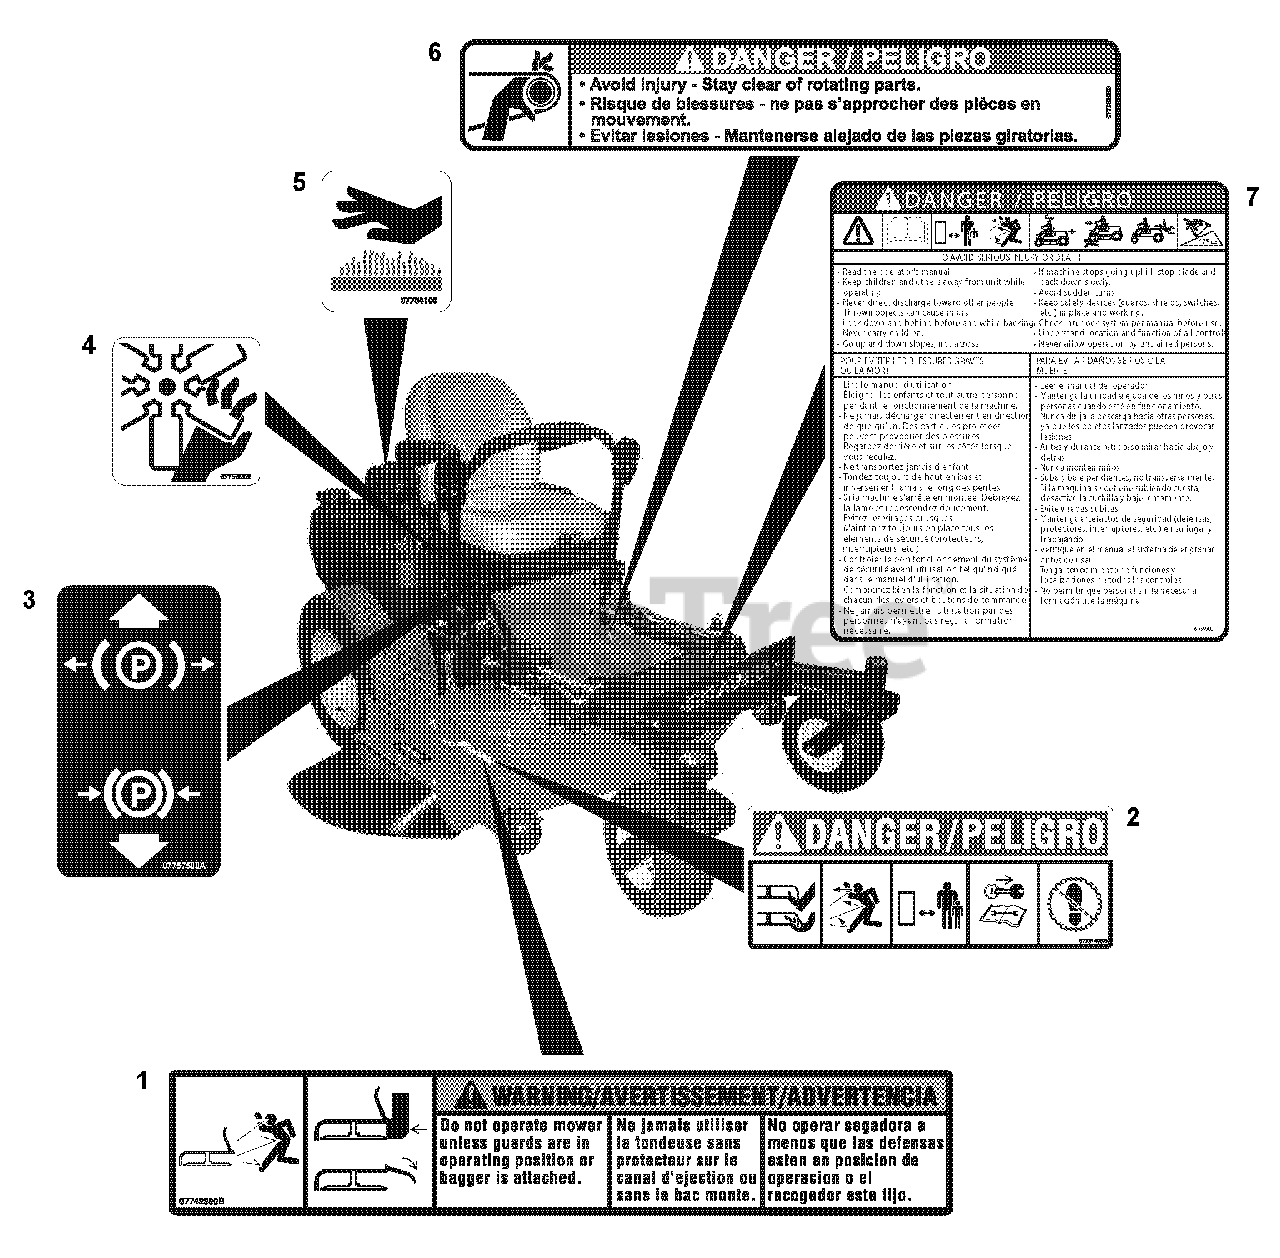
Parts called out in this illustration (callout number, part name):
1	Decal, Warning
2	Decal, Mower Pan Danger
3	Decal, Parking Brake Lever
4	Decal, Danger Fan
5	Decal, Hot Surface
6	Decal, Danger Rotating Parts
7	Decal, Danger- Bilingual
